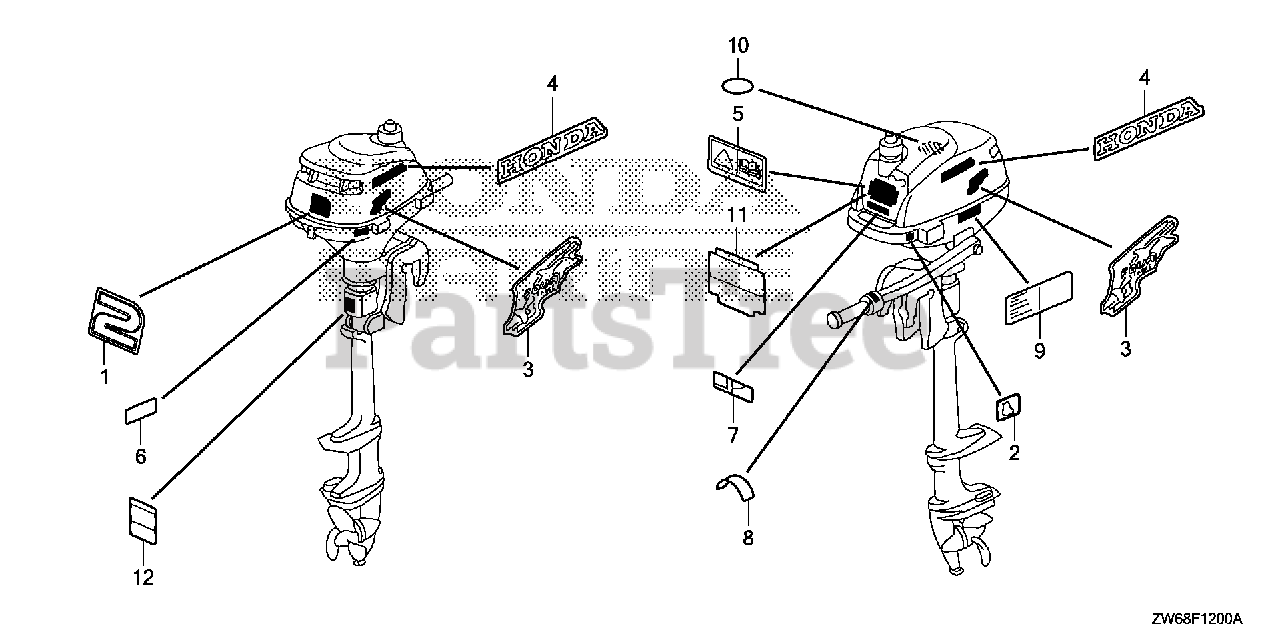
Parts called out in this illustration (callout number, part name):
2	MARK, EMERGENCY SWITCH INDICATION
6	MARK, FUEL PETCOCK (E)
8	MARK, THROTTLE (GRIP TYPE)(E)
10	LABEL, RECOIL CAUTION
